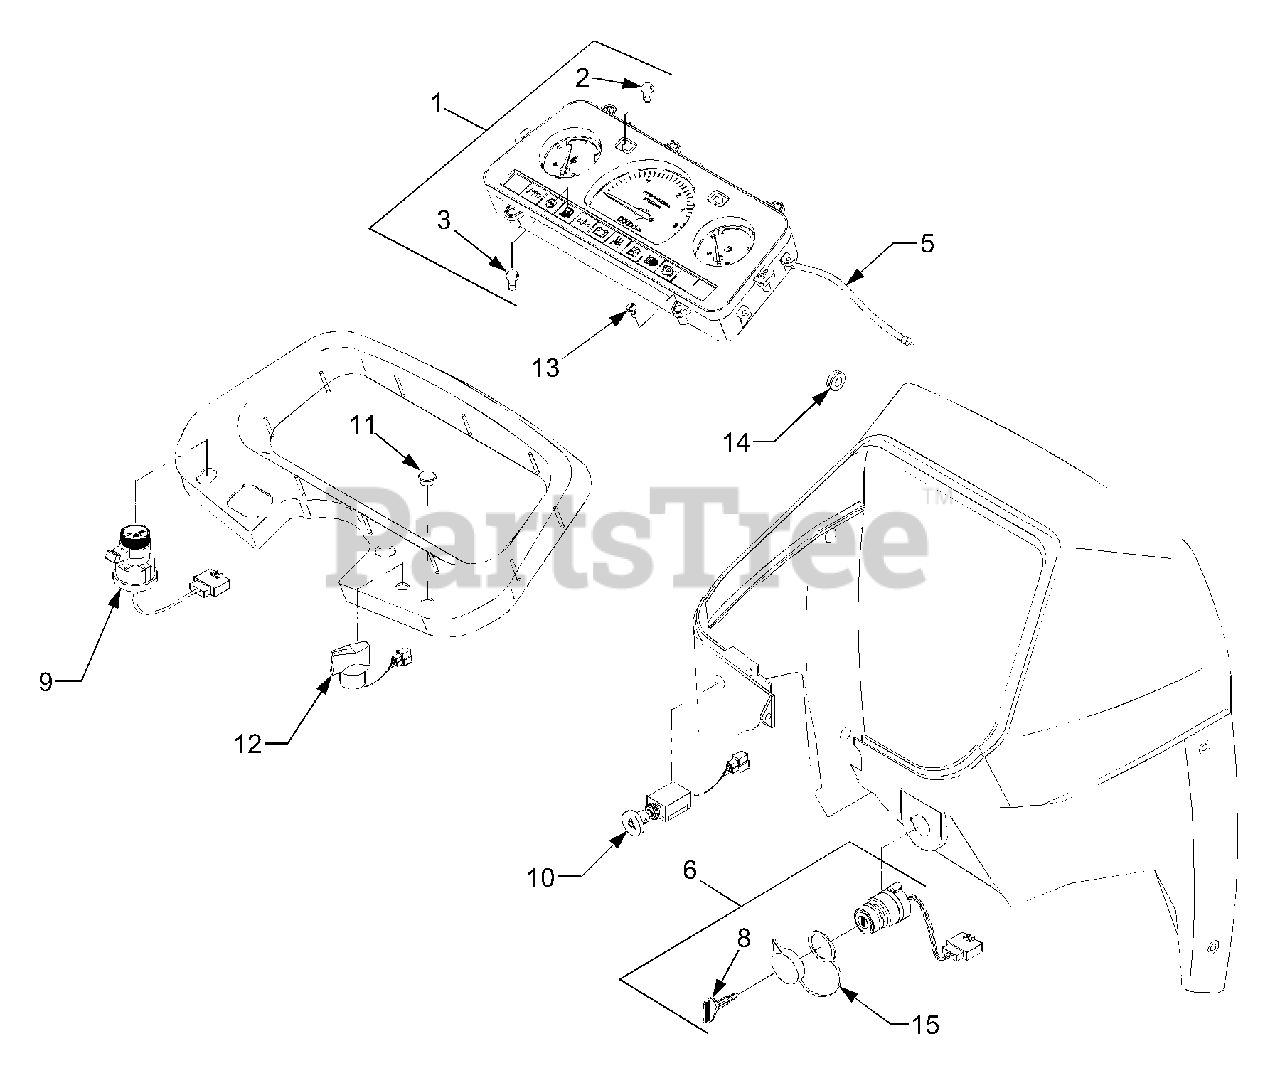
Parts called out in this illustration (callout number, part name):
1	Instrument Meter Ass'y
3	Bulb
5	Cable, Instrument Meter
6	Starter Switch
8	Key
9	Combination Switch Ass'y
10	Hazard Switch Ass'y
12	Switch, PTO
15	Cover, Starter Switch
